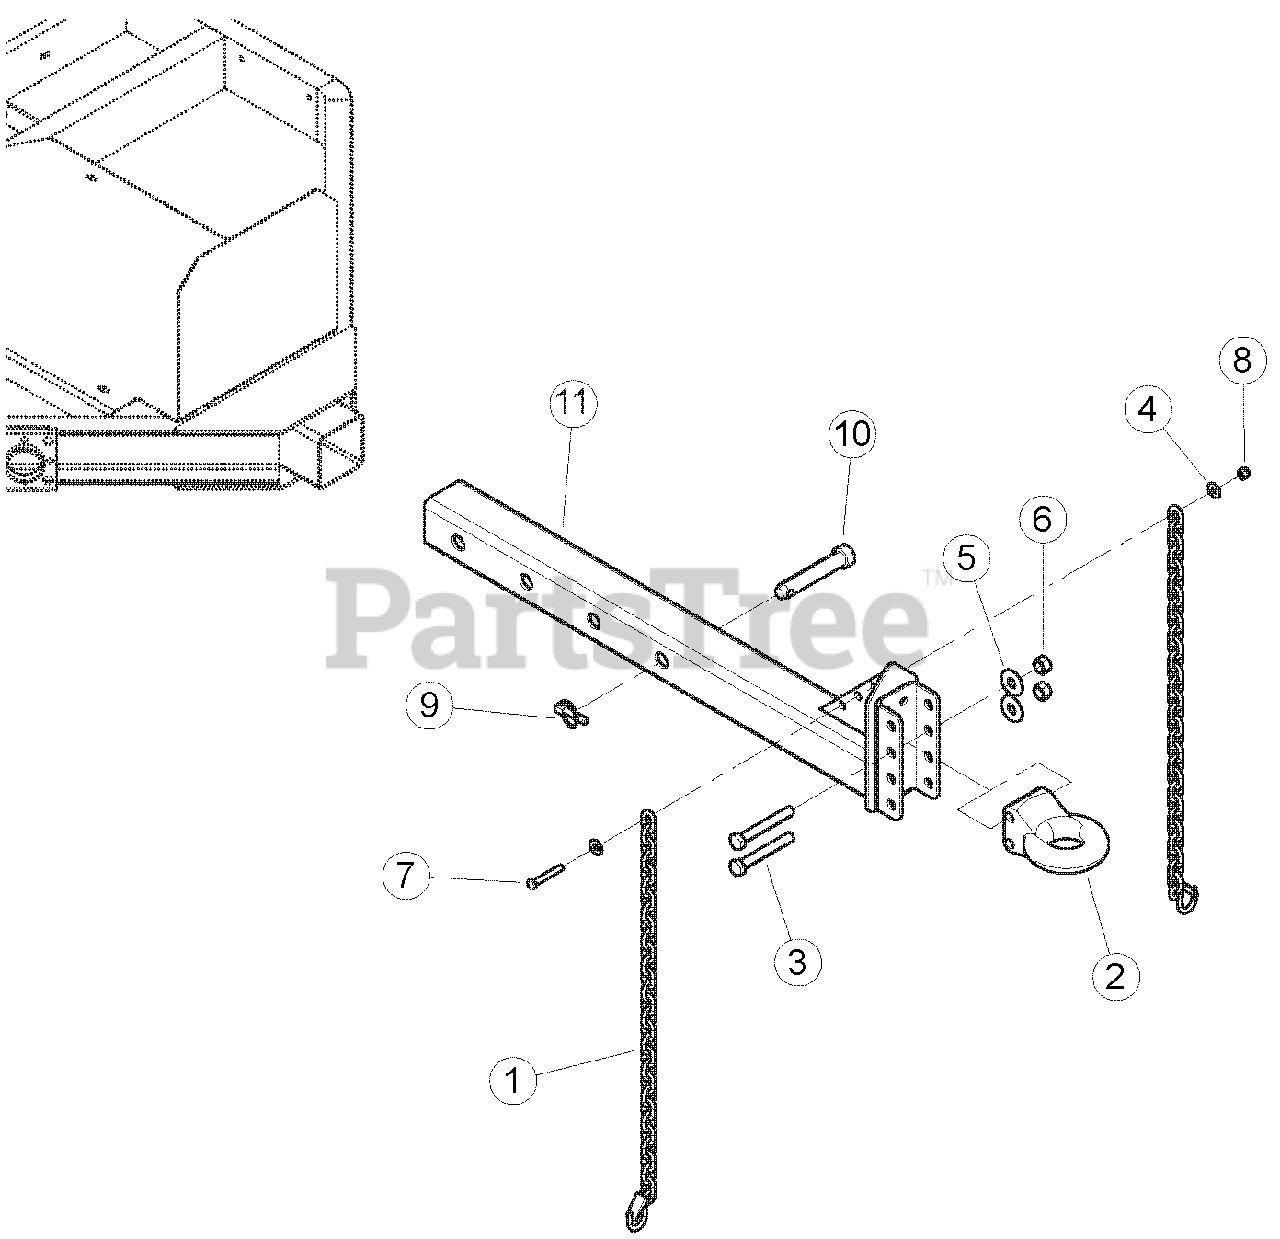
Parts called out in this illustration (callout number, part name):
1	CHAIN, SAFETY 5000 LB W/LATCH
2	HITCH, PINTLE RING, 20,000 LB
3	BOLT, 5/8 X 4-1/2 HEX HD G5 ZP
4	WASHER, 3/8" FLAT ZP (67PCS/LB)
5	WASHER, 5/8" FLAT ZP-37PCS/LB
6	NUT, 5/8" CENTERLOCK ZP GR5
7	BOLT 3/8 X 2-1/2 GR5 HHCS ZP
8	NUT, 3/8" NE NYLOCK ZP
9	PIN, 7/16 X 1-3/4 LYNCH
10	TOP LINK PIN, CAT 2
11	WELDMENT, HITCH POLE W/PLATE
